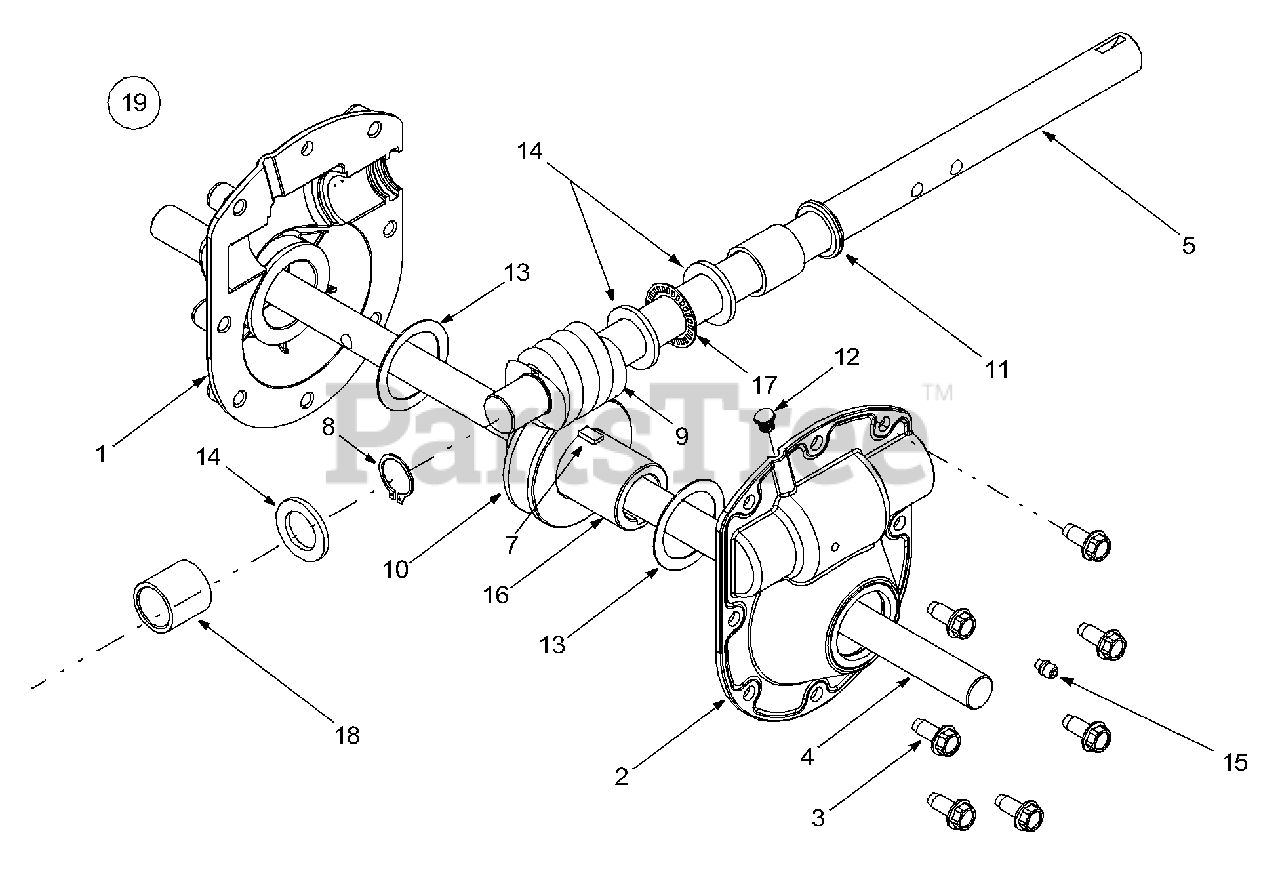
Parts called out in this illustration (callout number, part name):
1	Housing Assembly, RH
2	Housing Assembly, LH
3	Screw, 5/16-18 x 0.75
4	Axle, Auger
5	Shaft, Auger Drive
7	#91 Woodruff Key 1/4 x 3/4
8	Snap Ring .875 Dia.
9	Gear, Worm, Double Thread LH
10	Gear, Worm, LH
11	Seal, Oil .875 ID
12	Plug, 1/4 x .437
13	Washer, Flat, 1.52 x 2.0
14	Washer, Flat, .88 x 1.38
15	Lube Fitting, 3/16 Drive
16	Shaft, Worm Gear
17	Bearing, Thrust .877
18	Sleeve Bearing, .877 x .125 x 1.11
19	Auger Gearbox Assembly Complete
